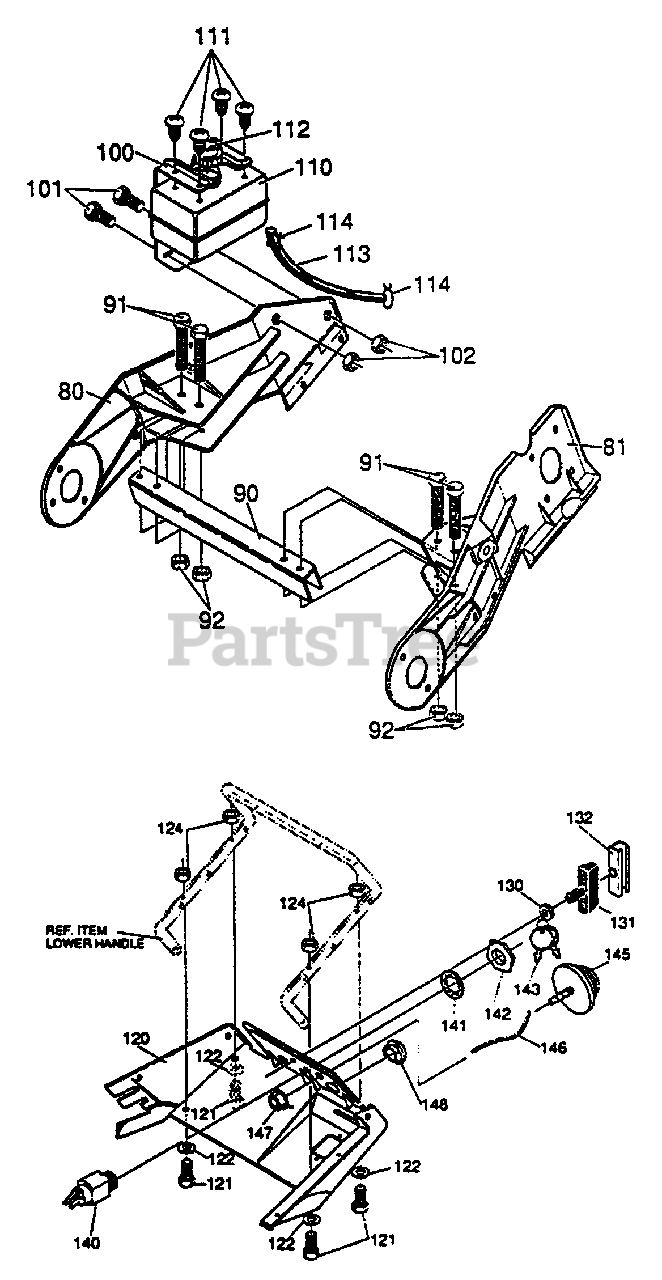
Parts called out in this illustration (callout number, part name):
80	FRAME, SIDE RH
81	FRAME, SIDE LH
90	CHANNEL, FRAME SUPPORT
91	SCREW, 1/4-20 X 2.00
92	NUT, 1/4-20
100	BRACKET, FUEL TANK
101	SCREW, 1/4-20 X .75
102	NUT, 1/4-20 REG HEX CTRLK
110	TANK, FUEL
111	SCREW, 1/4-14 X .88
112	CAP, GAS TANK 2CY
113	TUBING, GAS LINE 11.5 IN.
114	CLAMP, HOSE
120	COVER, BOTTOM
121	SCREW, 1/4-20 X 1.25
122	FLATWASHER .281 X .63 X .065
124	NUT, 1/4-20 REG HEX CTRLK
130	GROMMET & WASHER, ROPE GUIDE
131	KNOB, SHORT
132	INSERT METAL, KNOB
140	SWITCH, IGNIT
141	WASHER, REG INTLK.
142	NUT, 5/8-32
143	2 KEYS & RING
145	PRIMER, ENGINE
146	HOSE, PRIM
147	NUT, 1/4-20
